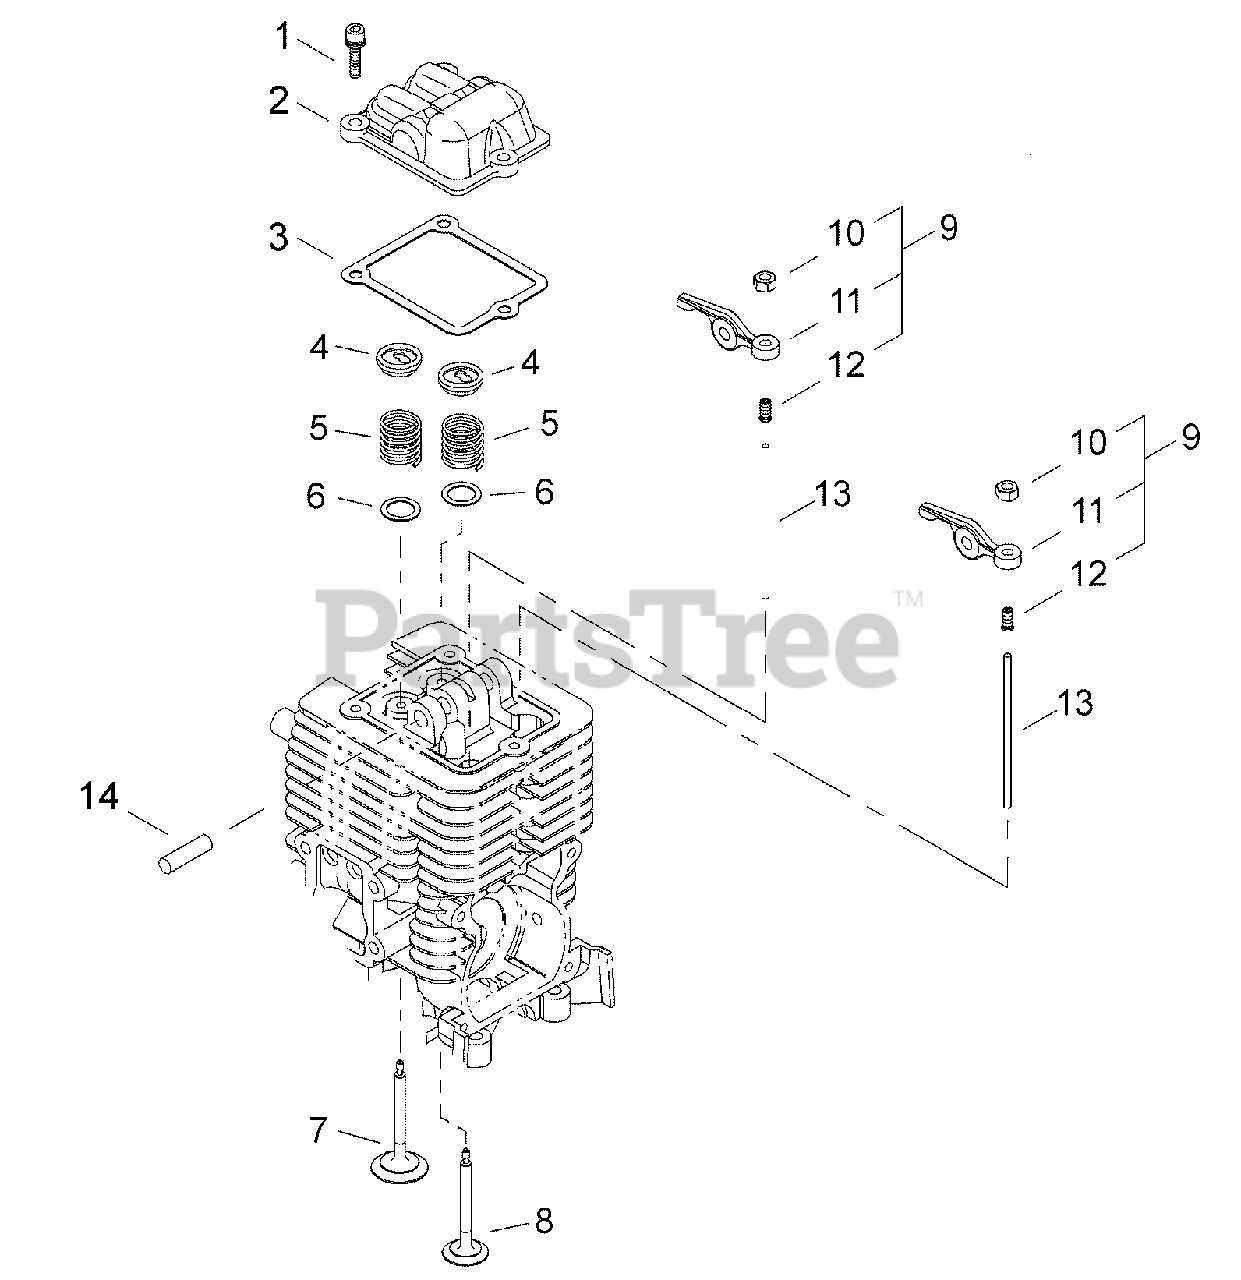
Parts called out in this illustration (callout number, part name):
1	SCREW - 4X14
2	COVER, ROCKER ARM
3	GASKET
4	RETAINER, VALVE
5	SPRING, VALVE
6	WASHER, VALVE - 9
7	VALVE, INTAKE
8	VALVE, EXHAUST
9	ROCKER ARM ASSY
10	LOCKNUT, ADJUSTER
11	ARM, ROCKER
12	SCREW, ADJUST
13	PUSHROD
14	SHAFT, ROCKER ARM - 5X37.8
